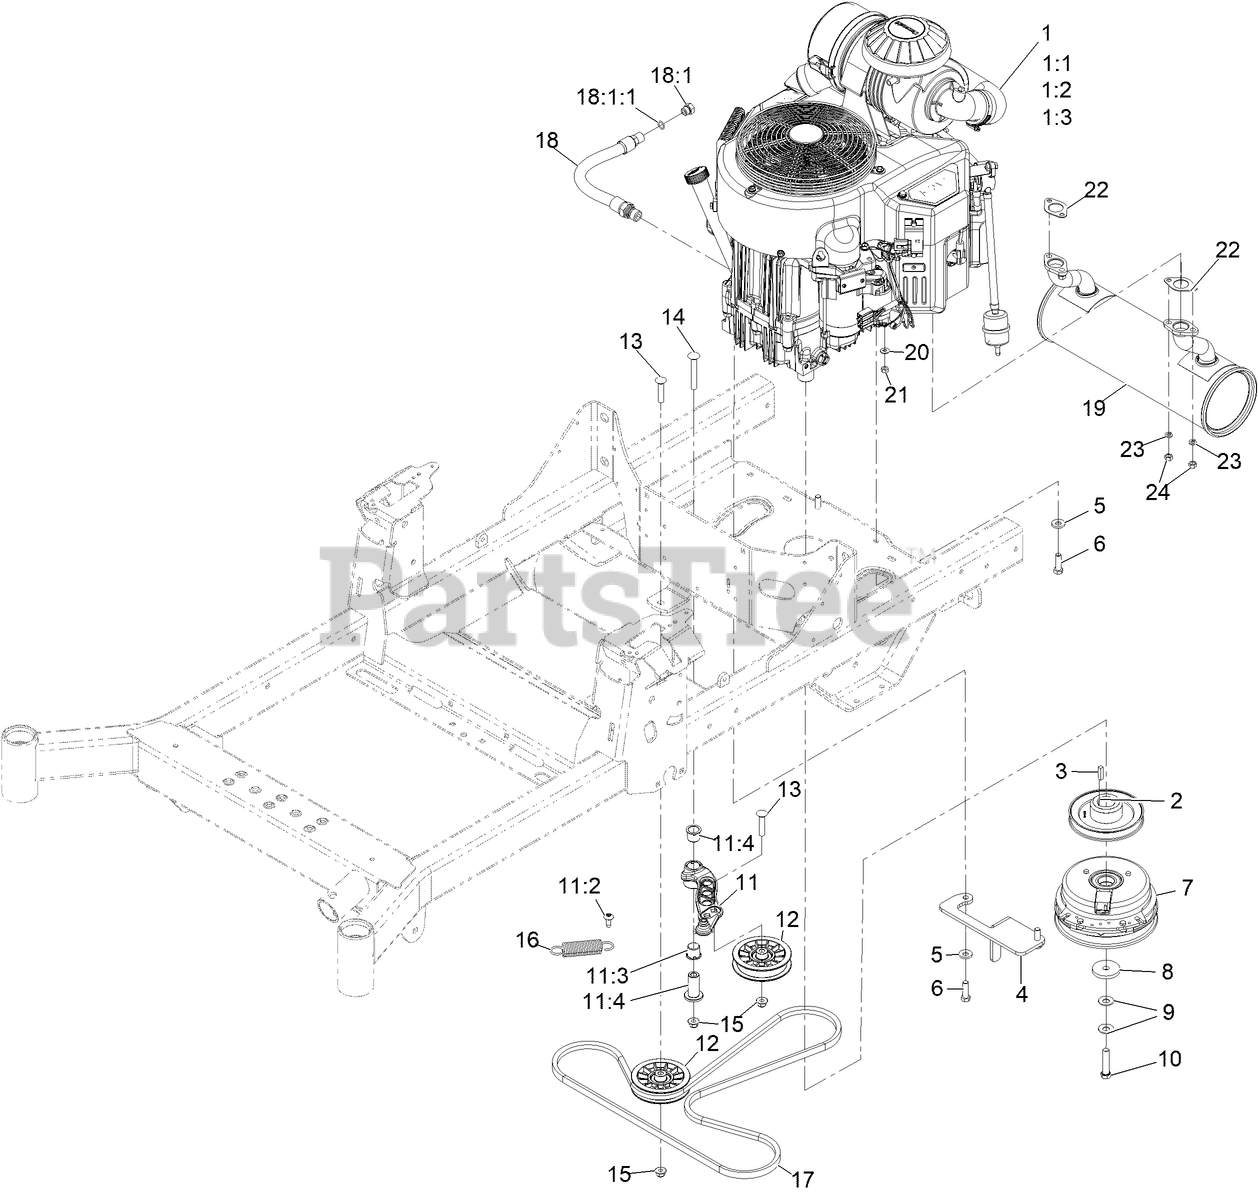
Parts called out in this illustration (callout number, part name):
1:1	KAWASAKI 49065-7010 ENGINE OIL FILTER
1:2	KAWASAKI 11013-7044 ENGINE AIR FILTER
1:3	KAWASAKI 11013-7045 SAFETY FILTER
2	SHEAVE, ENGINE
4	ANCHOR-CLUTCH
5	WASHER-BELLEVILLE
6	SCREW-HH
7	CLUTCH - 1.13
8	WASHER-CLUTCH
9	WASHER-SPRING
10	SCREW-HH W/LOCTITE
11	ASM, PUMP IDLER
11:2	SCREW, TAPTITE
11:3	BUSHING, IGUS
11:4	Spacer, Idler Pivot
12	PULLEY-FLAT IDLER
13	SCREW-CARR
14	SCREW-CARR
15	NUT-HF, NI
16	SPRING-EXTENSION
17	BELT-V
18	ENGINE OIL DRAIN HOSE ASM
18:1	PLUG-HH
18:1:1	O-RING
19	MUFFLER, KAWASAKI
20	WASHER-FLAT
21	NUT-HEX
22	GASKET-EXHAUST
23	WASHER-LOCK
